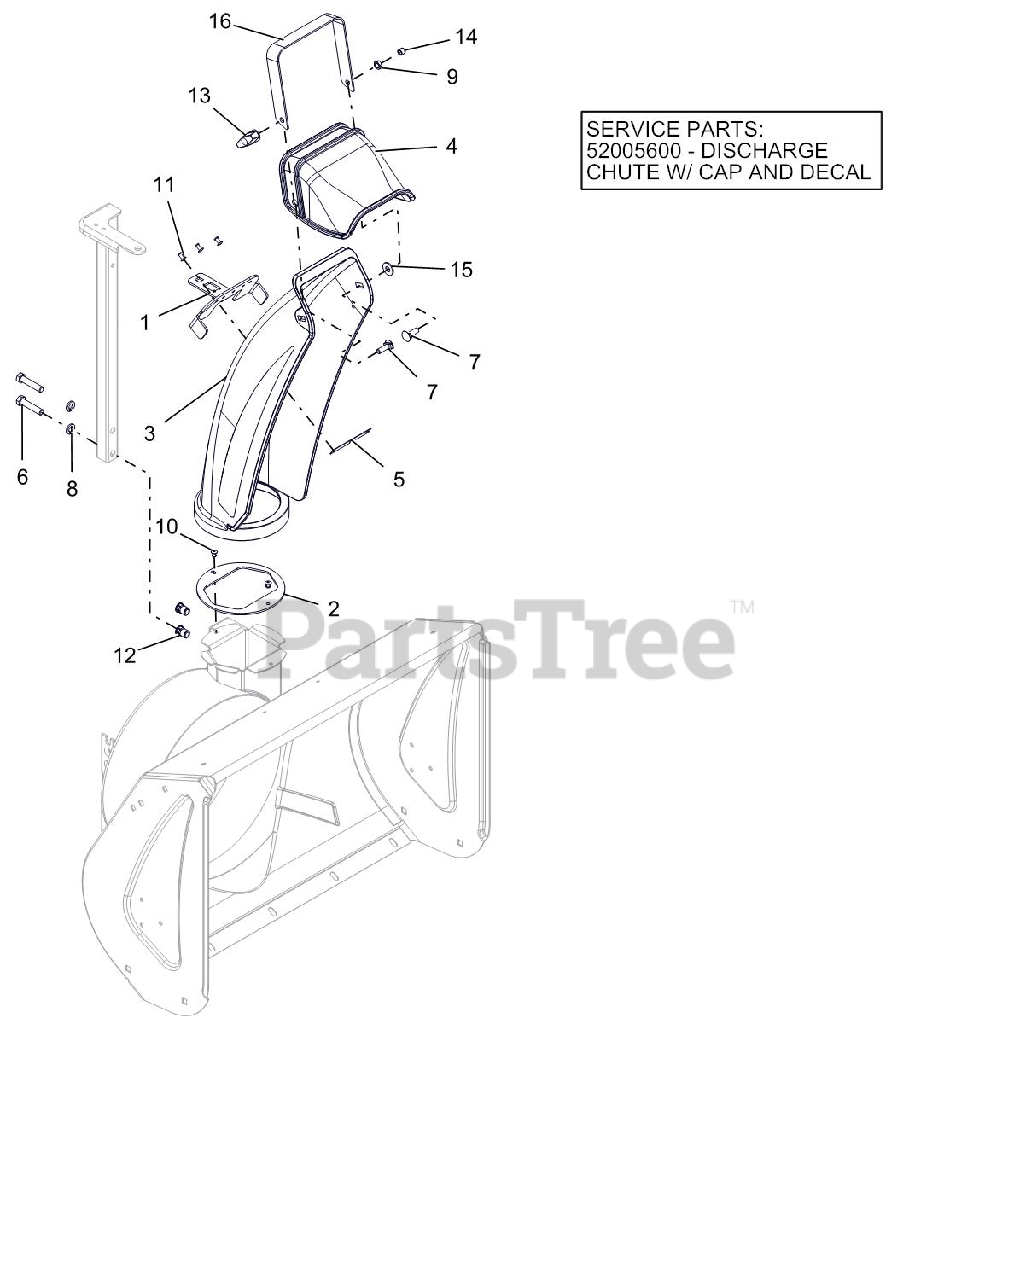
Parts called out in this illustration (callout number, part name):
1	CHUTE MOUNT BRACKET
2	BAFFLE, COMPACT DISCHARGE
3	CHUTE, PLASTIC DISCHARGE LONG
4	CAP,PLASTIC - SNOTEK (W/DECAL)
5	PLATE,CHUTE MOUNT BACKING
6	@BLT-HEX .38-16X1.75 GR5 YWZC
7	BLT,RNHDRECSHNK .31-18X1.00
8	@WSHR-LK .38X.094 REG YWZC
9	@NUT-LK-CTR-JAM .31-18 YWZC
10	RVT-POP .187 YZ
11	RIVET, #66 STEEL POP PD BLACK
12	NUT, THREADED INSERT .38-16
13	KNOB, WING .31-18 UNC
14	CAP, END .281X.313
15	@WSHR-FL-STL.38X.875X.083 YWZC
16	HANDLE, MANUAL CHUTE CAP
17	CHUTE, MANUAL DISCHARGE W/CAP
